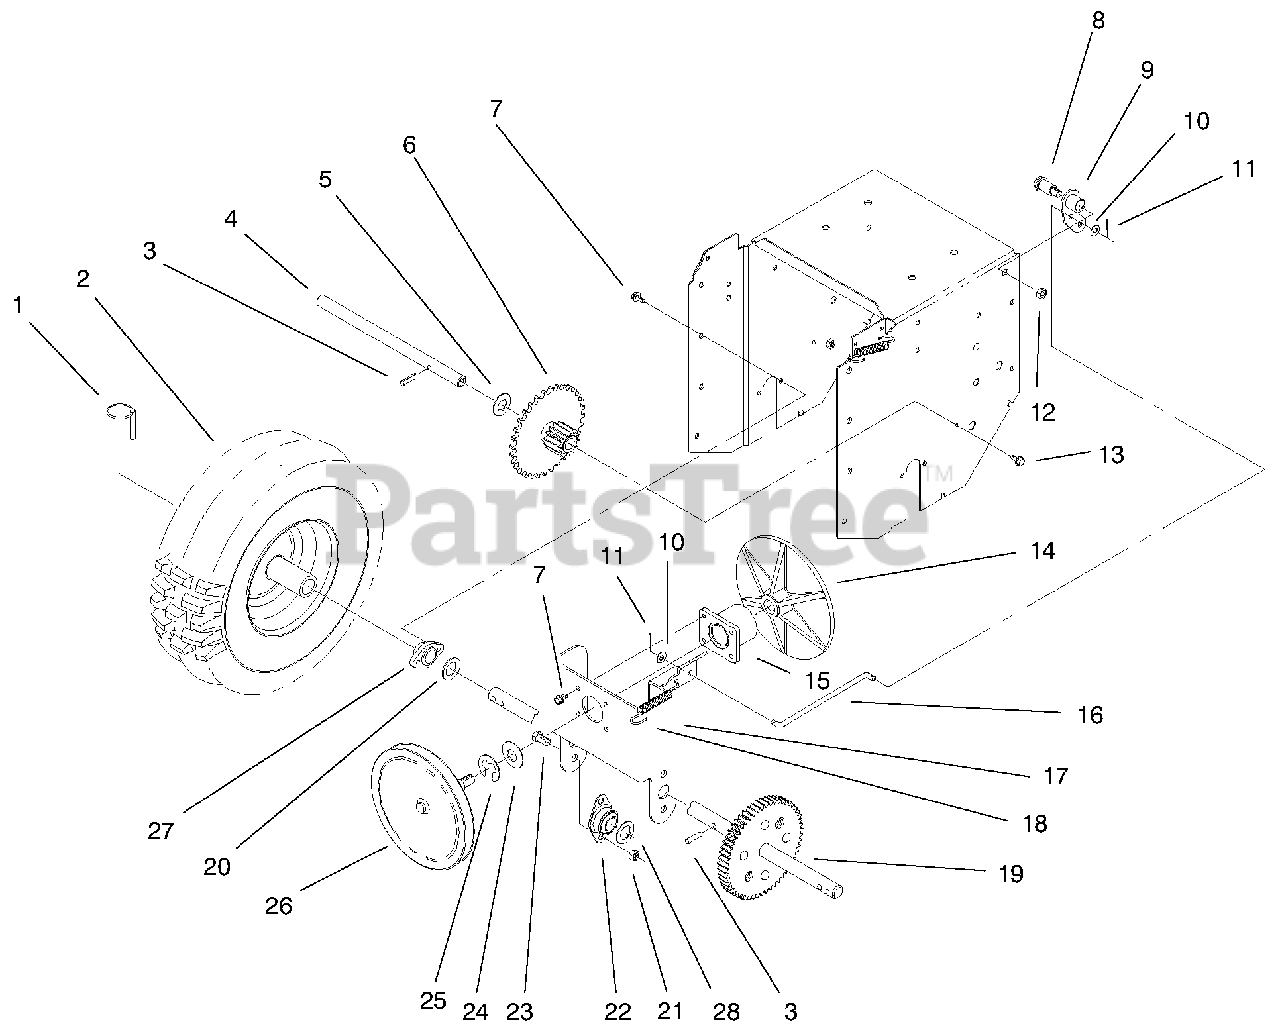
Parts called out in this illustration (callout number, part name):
1	Pin-Lynch
2	Wheel & Tire ASM 13.5
3	Pin-Spring
4	Shaft-Intermediate
6	ASM-Gear/Bushing
7	Screw-HH
8	Bolt-Shoulder
9	Wa-Pivot Hub
10	Black Zinc Wshr
11	Pin-Cotter
12	Nut-Lock
13	Screw-HWH
14	Disc-Friction Aluminum
15	ASM-Bearing Hub
16	Rod-Engage
17	Frame-Friction Plate
18	Spring-Engage
20	Thrust Washer
21	Nut-Lock
22	Bushing-Selt/A
23	Screw-HH
24	Bearing-Thrust
25	Snap Ring
26	ASM-Pulley/Shaft
27	Axle Brg
28	Thrust Washer
